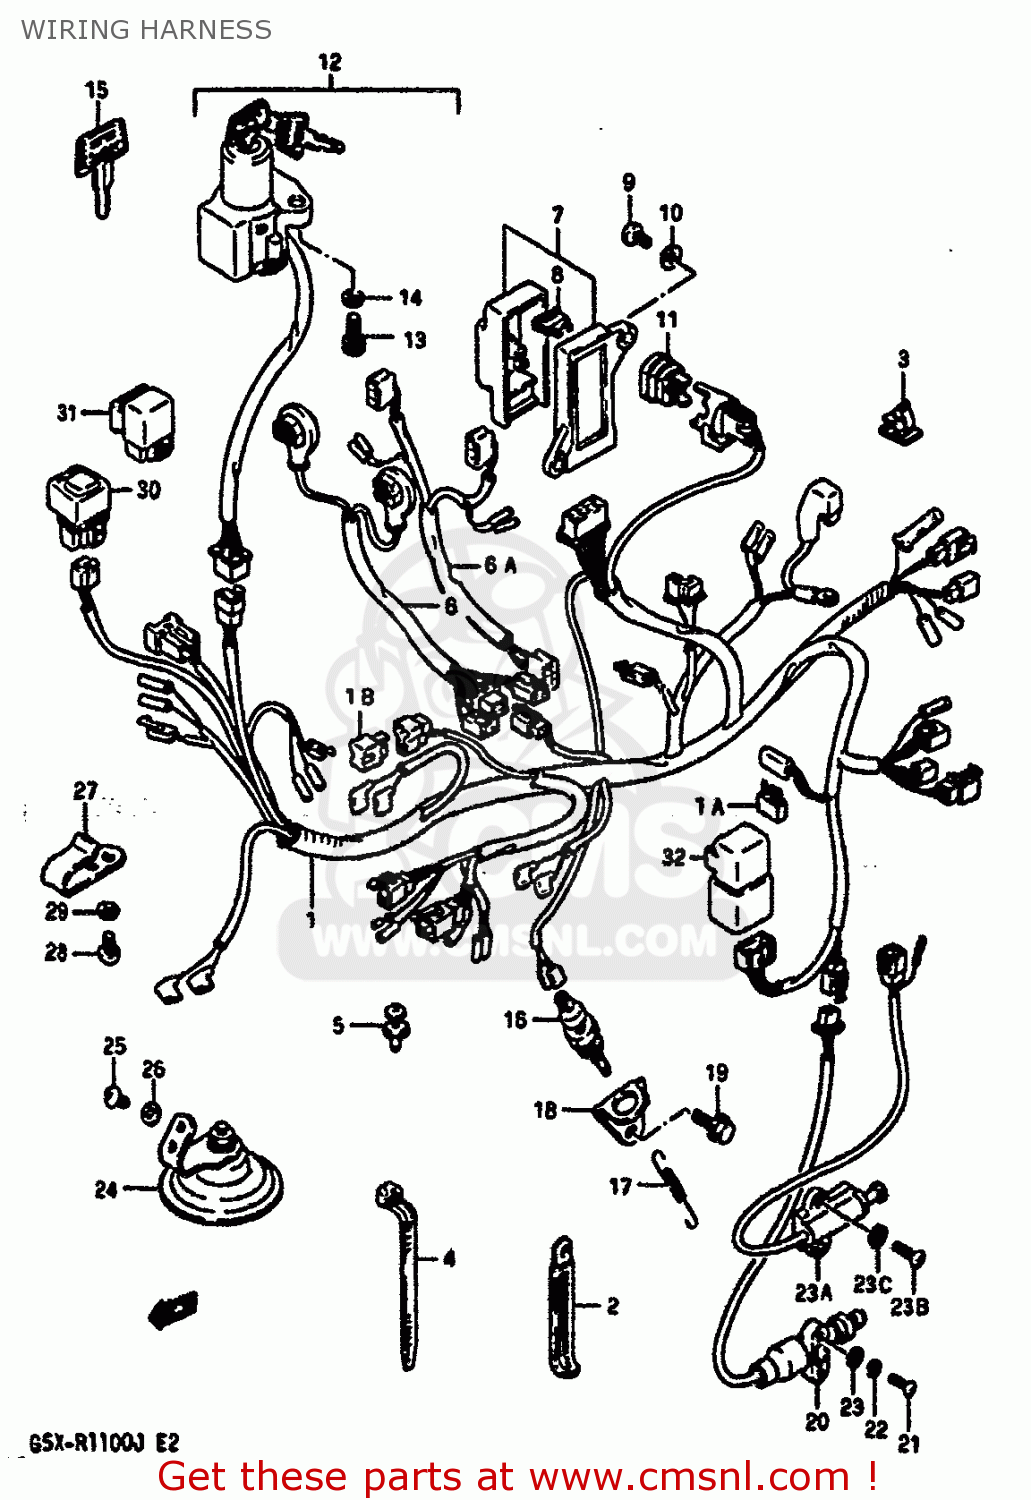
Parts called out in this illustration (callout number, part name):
1	HARNESS,WIRING
1A	DIODE(STANLEY DE8804)
2	CLAMP
3	CLAMP
4	CLAMP(L:125)
5	CLIP
6	WIRE,HEADLAMP LEAD
6A	WIRE,HEADLAMP LEAD
7	BOX ASSEMBLY,FUSE
8	FUSE(10A)
9	SCREW 6X12
10	WASHER
11	BREAKER ASSY,CIRCUT
12	SWITCH ASSY,IGNITION
13	BOLT
14	WASHER,LOCK
15	KEY,BLANK
16	SWITCH ASSY,STOP LAMP
17	SPRING
18	BRACKET,STOP LAMP SWITCH
19	BOLT
20	SWITCH ASSY,SIDE STAND WARN
21	SCREW 5X20
22	WASHER,LOCK
23	WASHER,5MM
23A	SWITCH ASSEMBLY,SIDE STAND
23B	SCREW
23C	WASHER,LOCK
24	HORN ASSEMBLY
25	SCREW
26	WASHER
27	CLAMP,HANDLE SWITCH LEVER
28	SCREW
29	WASHER,LOCK
30	RELAY, ANTINOSE DIVE FORK
31	RELAY ASSY,HEADLAMP
32	RELAY ASSEMBLY
